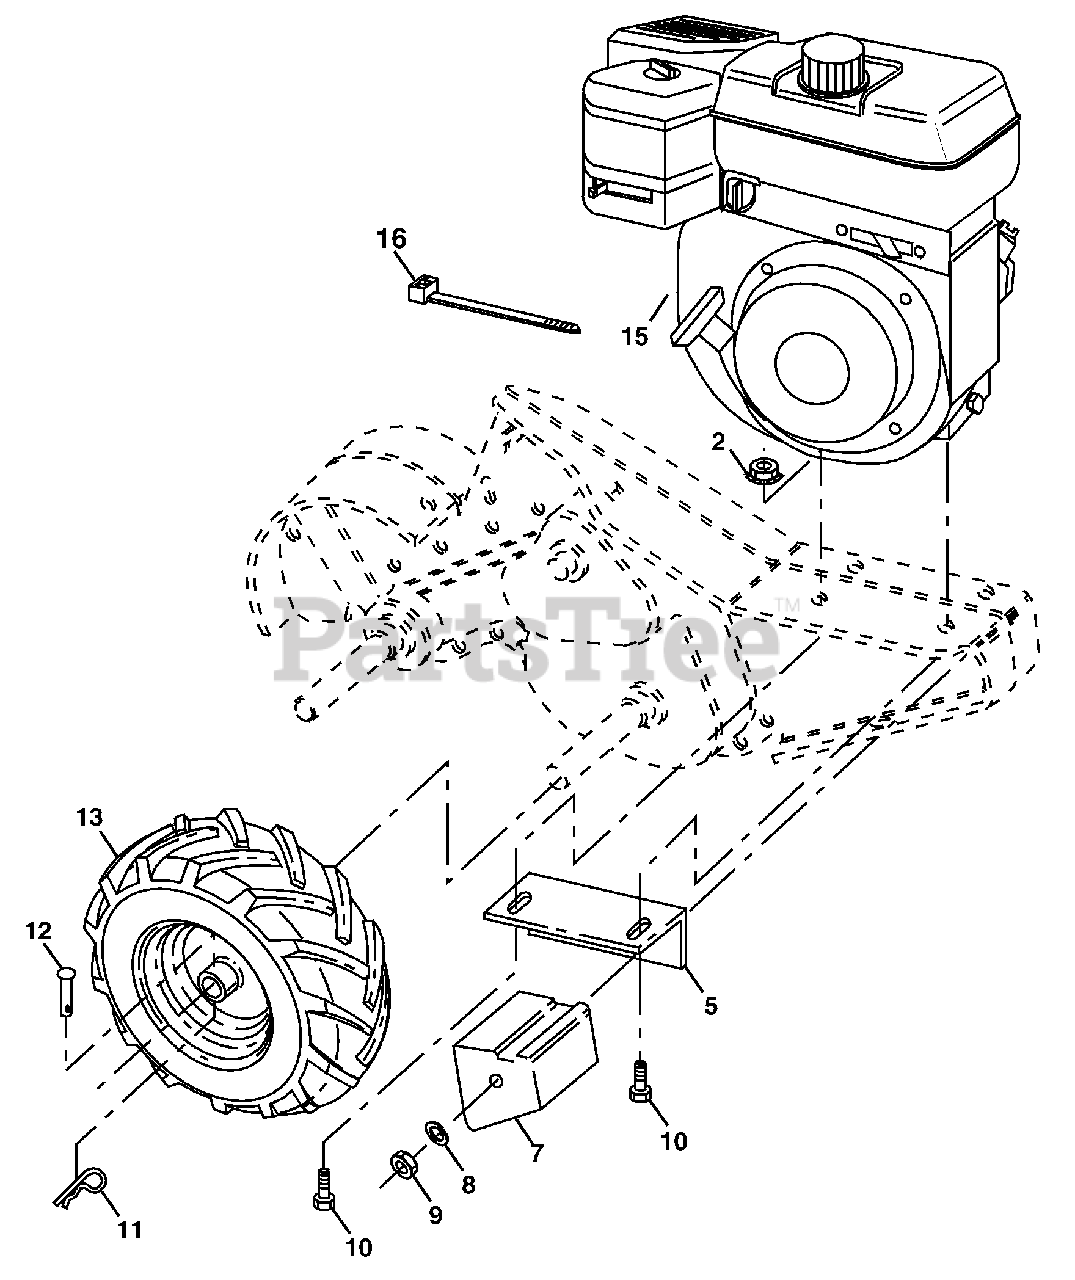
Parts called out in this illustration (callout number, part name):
2	Nut, Hex Flange
5	Bracket, Reinforcement
7	Counter Weight, R.H.
8	Washer, Lock 3/8
9	Nut, Hex 3/8-16
10	Bolt, Hex 5/16-18 x 1-1/2
11	Clip, Hairpin
12	Rivet, Drilled
13	Tire
13	Rim
13	Tire Valve
16	Tie Cable
